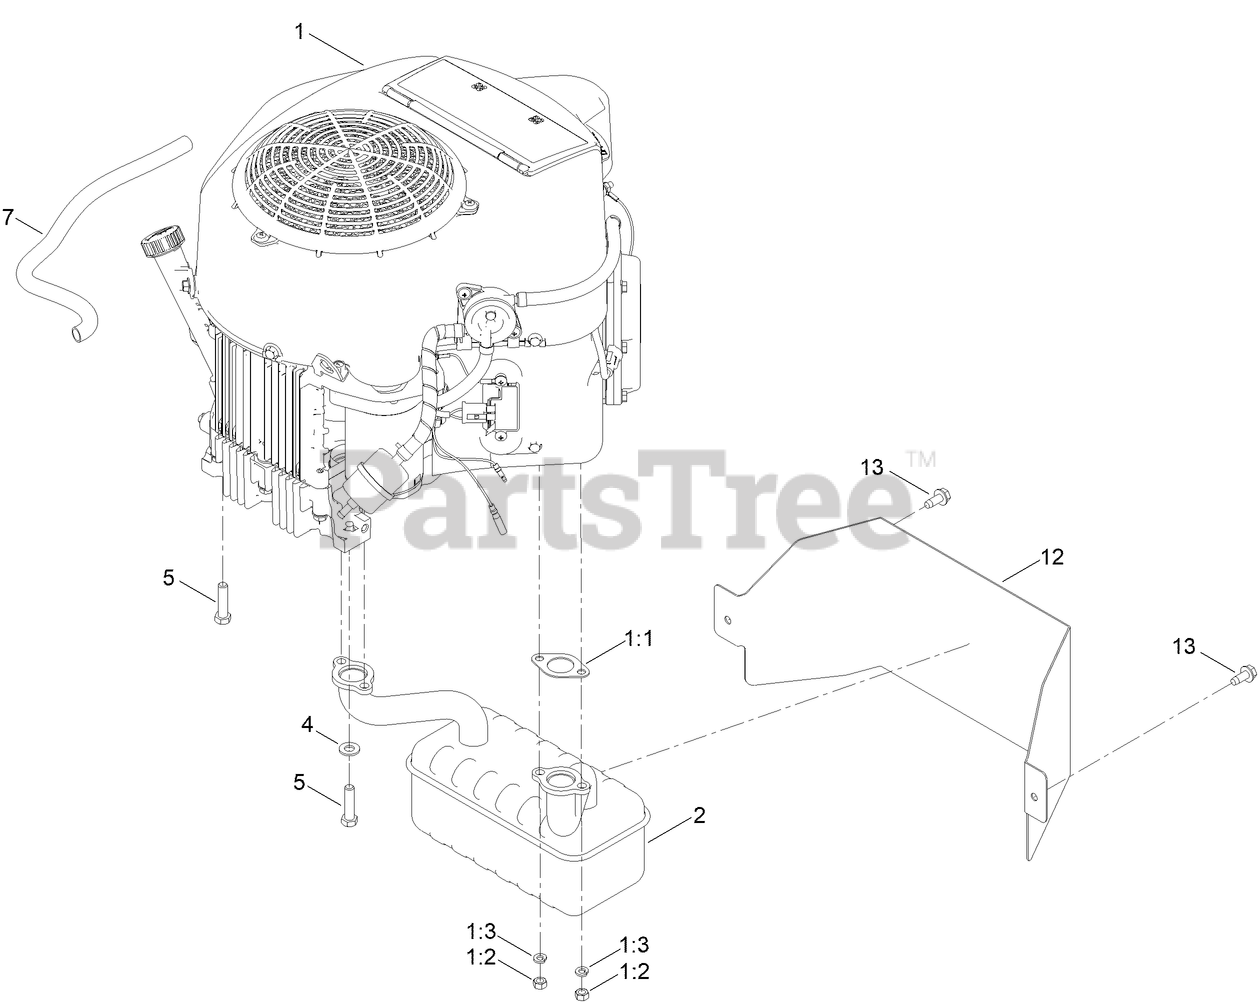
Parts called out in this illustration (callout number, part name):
1:1	GASKET-EXHAUST
1:3	WASHER-LOCK
2	MUFFLER
4	WASHER-FLAT
5	SCREW-HH
7	TUBE-DRAIN, OIL
12	HEAT SHIELD - MUFFLER
13	SCREW-HWHTF
